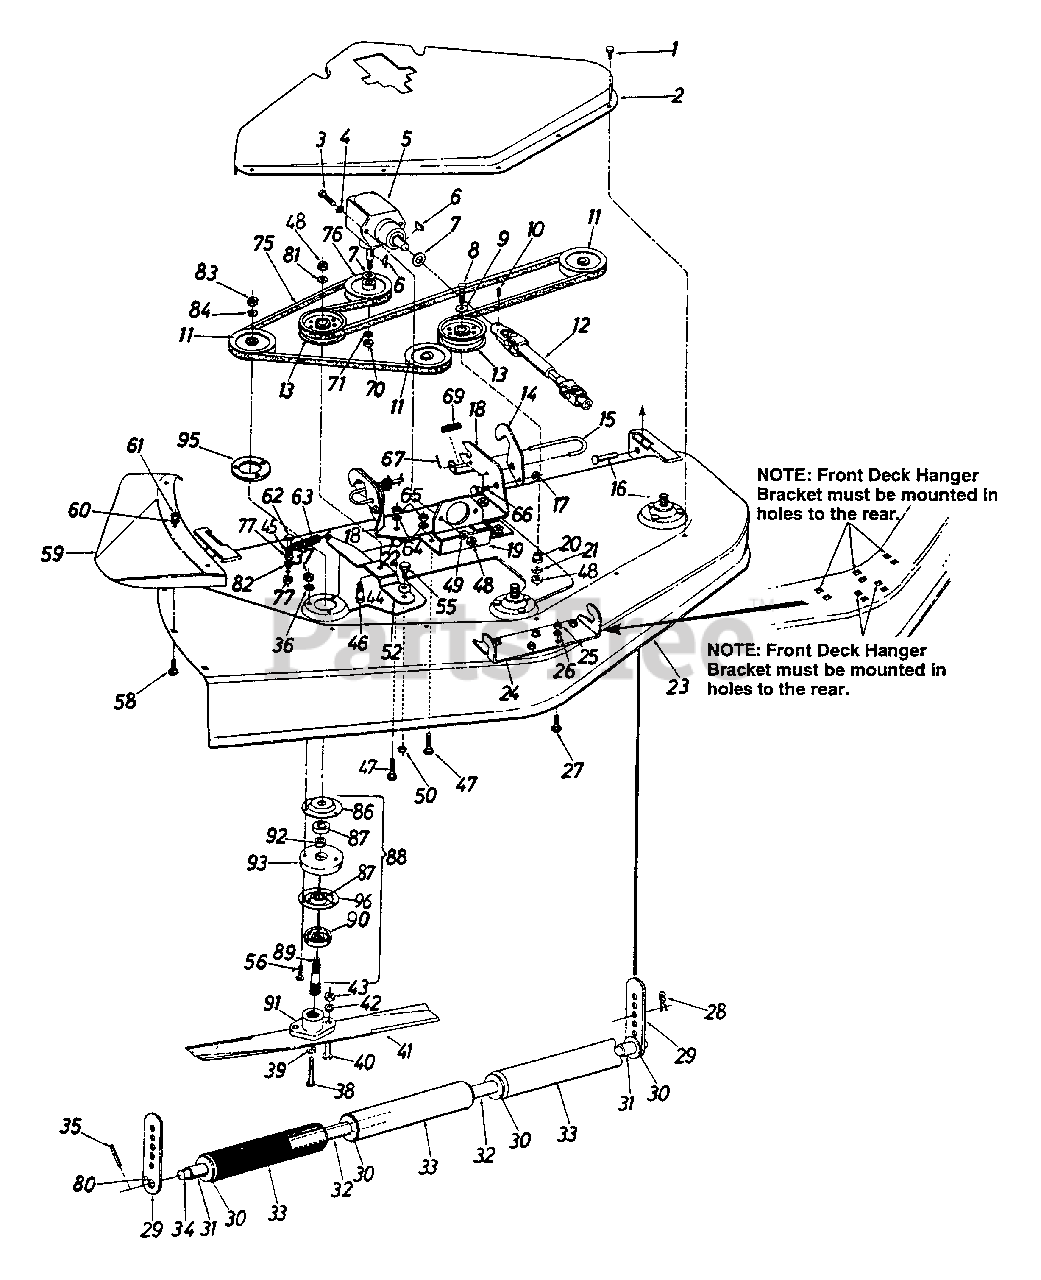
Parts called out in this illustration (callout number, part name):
1	Hex 8-Tap Scr. 1/4-20 x .38" Lg.
4	Ext. L-Wash. 3/8" I.D.
5	Right Angle Drive
6	#9 Hi-Pro Key 3/16 x 3/4" Dia.
7	Fl-Wash. 29/32" I.D.
8	Hex Bolt 3/8-16 x 2.25" Lg.
9	Fl-Wash. 3/8" I.D.
10	Sq. Hd. Set Scr. 3/8-16 x .50"
11	Deck Pulley
12	Universal Drive Shaft Ass'y.
12	Universal Drive Male Half
12	Universal Drive Female Half
13	Deck Idler Pulley
14	Hanger Lock
15	Release Pin
16	Clevis Pin .50" Dia.
17	Hex L-Nut 5/16-18 Thd.
21	L-Wash. 3/8" I.D.
22	Spacer .33" I.D. x .88" O.D.
26	L-Wash. 5/16" I.D.
27	Carriage Bolt 5/16-18 x .75" Lg.
28	Internal Cotter Pin
30	Fl-Wash. .75" I.D. x 1.5" O.D.
31	Spacer .758" I.D. x 1.25" O.D. x .530
34	Roller Shaft
35	Roll Pin 3/16 x 1.25"
36	L-Wash. 5/16" I.D.
37	Hex Cent. L-Nut 5/16-24 Thd.
38	Hex Self-Tap Scr. 3/8-24 x .75" Lg. (Gr. 5)
38	Hex Bolt 3/8-24 x .88" Lg. (Gr. 5)
39	L-Wash. 3/8" I.D. H.D.
40	Hex Bolt 5/16-24 x 1" Lg.
41	Blade 17"
42	L-Wash. 5/16" I.D.
43	Hex L-Nut 5/16-24 Thd.
44	Spr. Wash..445" I.D.
45	Fl-Wash. 1/4" I.D.
46	Shld. Scr. .625" Dia. x .96"
47	Carriage Bolt 5/16-18 x 1.5" Lg.
48	Hex Nut 3/8-16 Thd.
49	L-Wash. 3/8" I.D.
50	Hex L-Nut 7/16-14 Thd.
56	Hex Bolt 5/16-24 x 1.5" Lg. (Grade 5)
56	Screw-Rib Neck 5/16-24 x 1.12" Lg.
58	Carriage Bolt 5/16-18 x .75" Lg.
60	L-Wash. 5/16" I.D.
61	Hex Nut 5/16-18 Thd.
62	Hex Bolt 1/4-28 x 1-3/4" Lg.
63	Extension Spring
64	L-Wash. 5/16" I.D.
65	Hex Nut 5/16-18 Thd.
66	Shld. Bolt
67	Roll Pin 1/8" Dia.
69	Compression Spring
70	Hex L-Nut 5/8-18 Thd.
71	L-Wash. 5/8" I.D.
75	V-Belt 1/2"
76	Drive Pulley
77	Hex L-Nut 1/4-28 Thd.
80	Spring Pin Spiral 1/4" Dia. 1.00" Lg.
81	Bell-Wash. 3/8" I.D. x . 87" O.D.
82	L-Wash. 1/4" I.D."
83	Hex Jam Nut 5/8-18 Thd.
84	L-Wash. 5/8" I.D.
86	Bearing Housing
87	Ball Bearing
88	Deck Spindle Assembly 3/4"
88	Deck Spindle Assembly 1"
89	Spindle 3/4"
90	Bearing Shield
91	Blade Adapter 3/4"
91	Blade Adapter 1"
92	Spacer
95	Spindle Reinforcement Plate
96	Open Bearing Housing
96	Bearing Housing w/bearing 741-0919A
12649-0638	GUARD-CHUTE - MTD/TROY-BILT RED (0638)
12649-0648	GUARD-CHUTE - TECH GRAY (0648)
12650-4008	Height Adjuster - WINE RED (4008)
